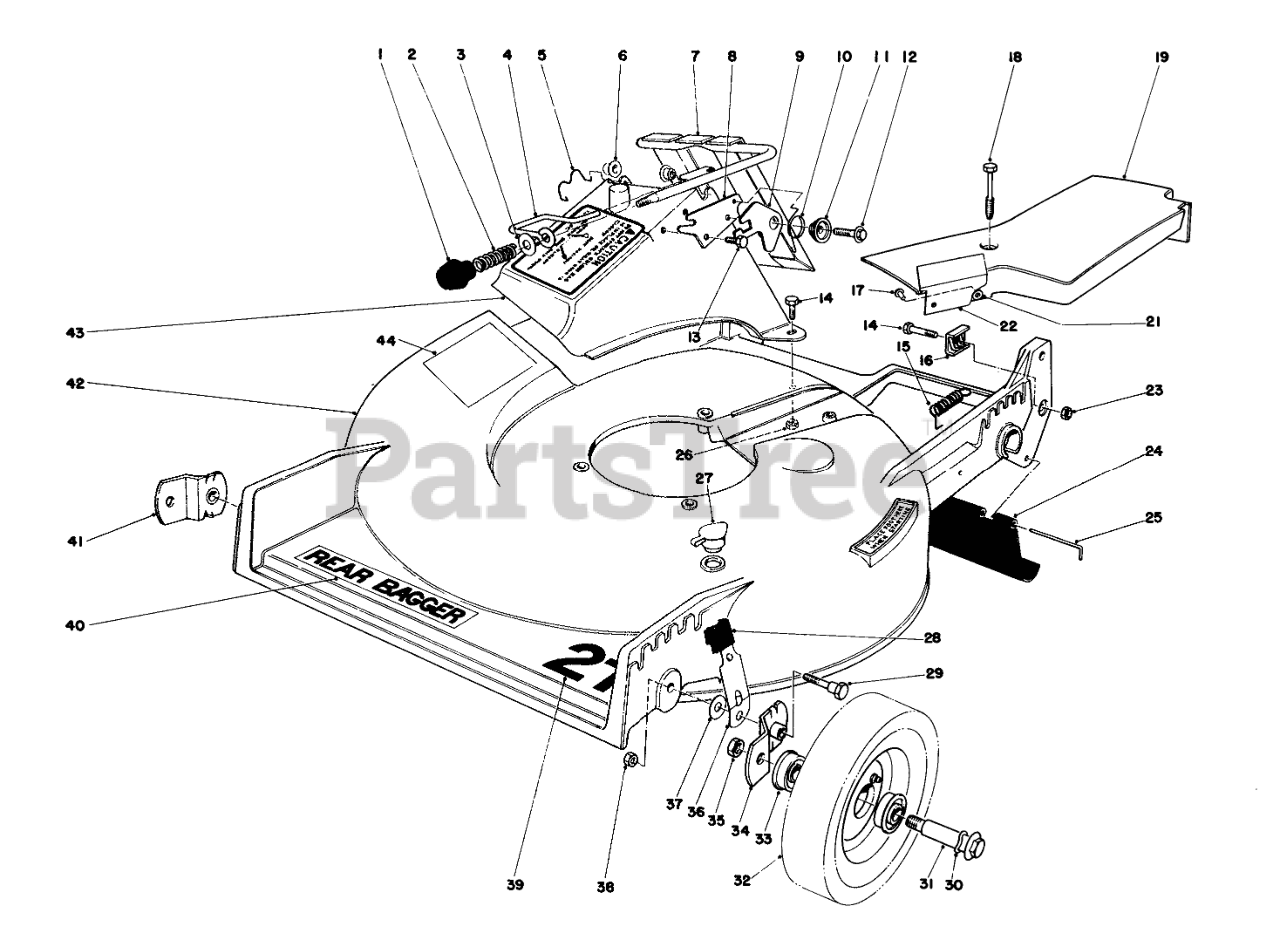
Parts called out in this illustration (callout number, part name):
2	COMPRESSION SPRING
3	WASHER
4	DOOR LATCH
5	DOOR RETAINER
6	BUSHING-NYLON
7	DOOR & HANDLE WA
8	DOOR LATCH PLATE
9	Latch Safety
10	TORSION SPRING
11	Latch Spacer
12	Screw
13	SCREW-HWH
14	SCREW-HH
15	IDLER SPRING
16	CLAMP-CABLE
17	RIVET-HEAD, FLAT
18	SCREW-HHFTF
19	Belt Cover (Incl. Ref. #17 & 21-22)
21	WASHER-FLAT
22	HEAT SHIELD
23	NUT-JAM
24	SHIELD - TRAILING
25	Rod Shield
26	NUT-LOCK, NI
27	WASHOUT PLUG
28	KNOB-ARM
29	PIVOT SCREW
30	SPRING WASHER
32	Wheel & Tire Assembly (Incl. Ref. #33)
33	BEARING-BALL
34	PIVOT ARM ASM A
35	Nut
36	SPRING ARM ASM (R&S)
37	WASHER-PIVOT
38	Nut
39	Decal 21"
40	DECK DECAL
41	PIVOT ARM ASM B
42	Housing
43	DISCHARGE CHUTE B
44	Decal-Caution (French & Dutch)
